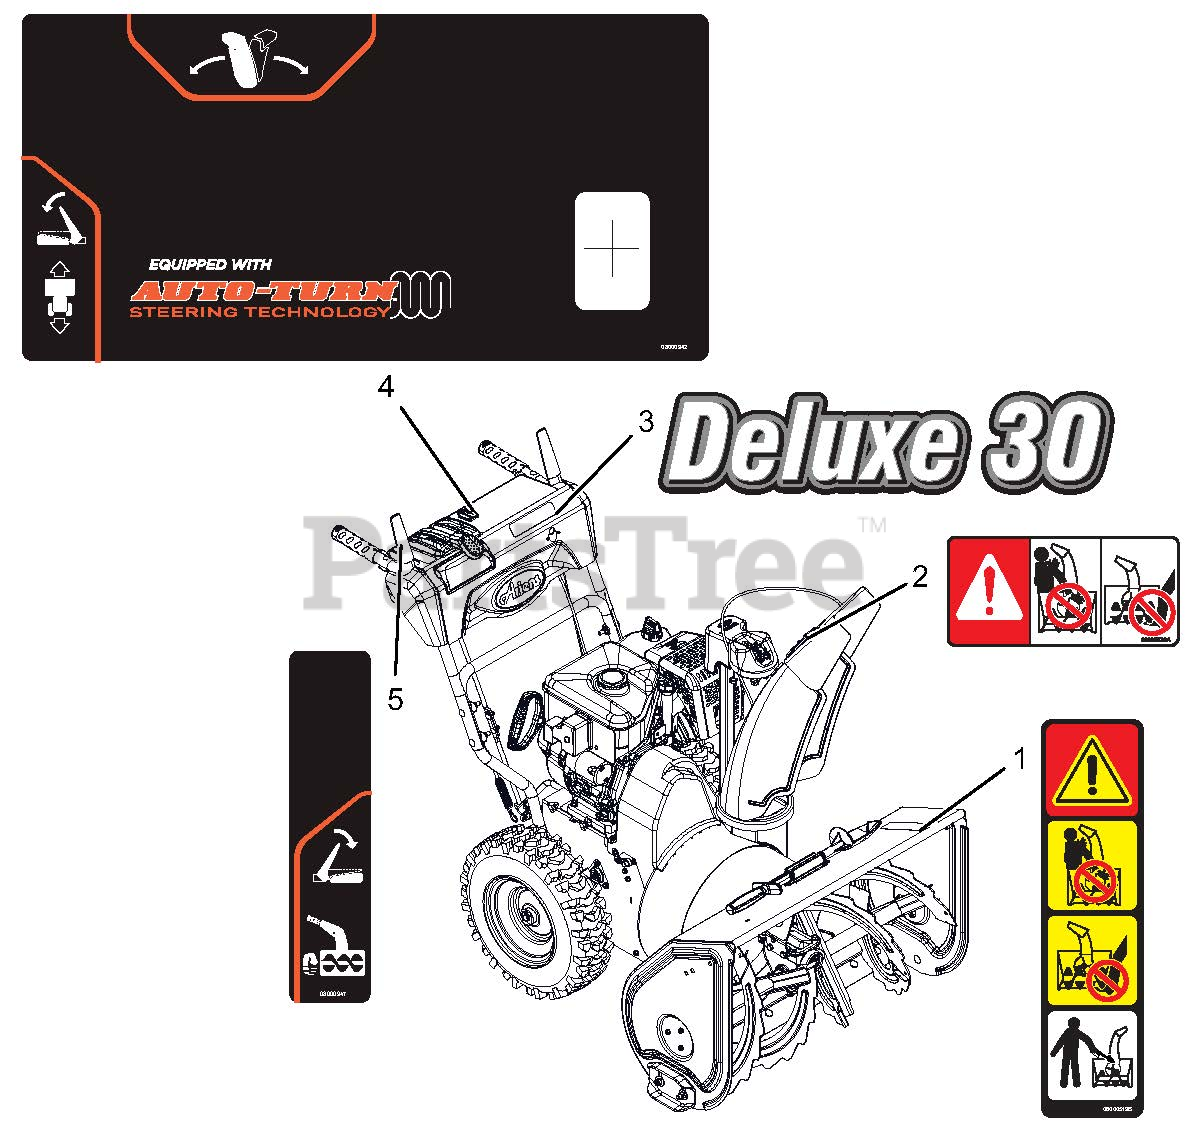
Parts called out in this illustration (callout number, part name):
1	DECAL, DANGER - ROTATING PARTS
2	DECAL, DANGER
3	DECAL, DELUXE 30
4	DECAL,CONTROL-LG ID
5	DECAL,CONTROL-RH CONTROL
